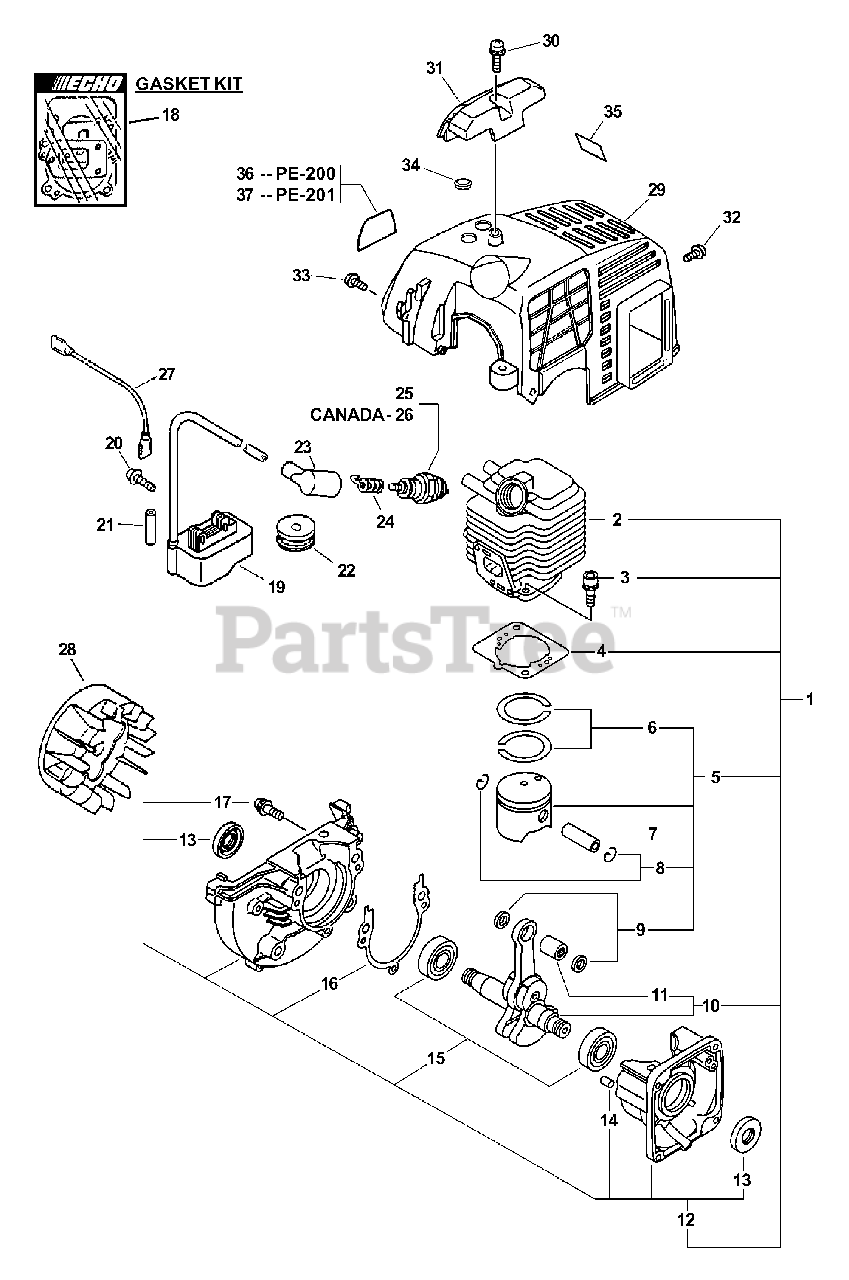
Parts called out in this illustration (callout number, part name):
1	SHORT BLOCK
2	CYLINDER
3	BOLT 5×22
4	GASKET, CYLINDER
5	PISTON KIT
6	RING, PISTON
7	PIN, PISTON 8
8	RING, SNAP
9	WASHER, THRUST
10	CRANKSHAFT ASSY
11	BEARING, NEEDLE 8
12	CRANKCASE KIT
13	SEAL, OIL 12
14	PIN, LOCATING 4
15	BEARING, BALL - 6201 C3
16	GASKET, CRANKCASE
17	BOLT 5×28
18	GASKET KIT
19	COIL, IGNITION
20	BOLT 4×20
21	TUBE, INSULATOR
23	CAP, SPARK PLUG
24	TERMINAL, SPARK PLUG
25	SPARK PLUG - BPM8Y
26	SPARK PLUG - BPMR8Y
27	LEAD - GROUND
28	FLYWHEEL
29	COVER, ENGINE
30	SCREW 5×16
31	GUARD, TOP
32	BOLT 4×8
33	SCREW 4×12
35	LABEL, CAUTION - HOT
36	LABEL, MODEL
37	LABEL, MODEL
